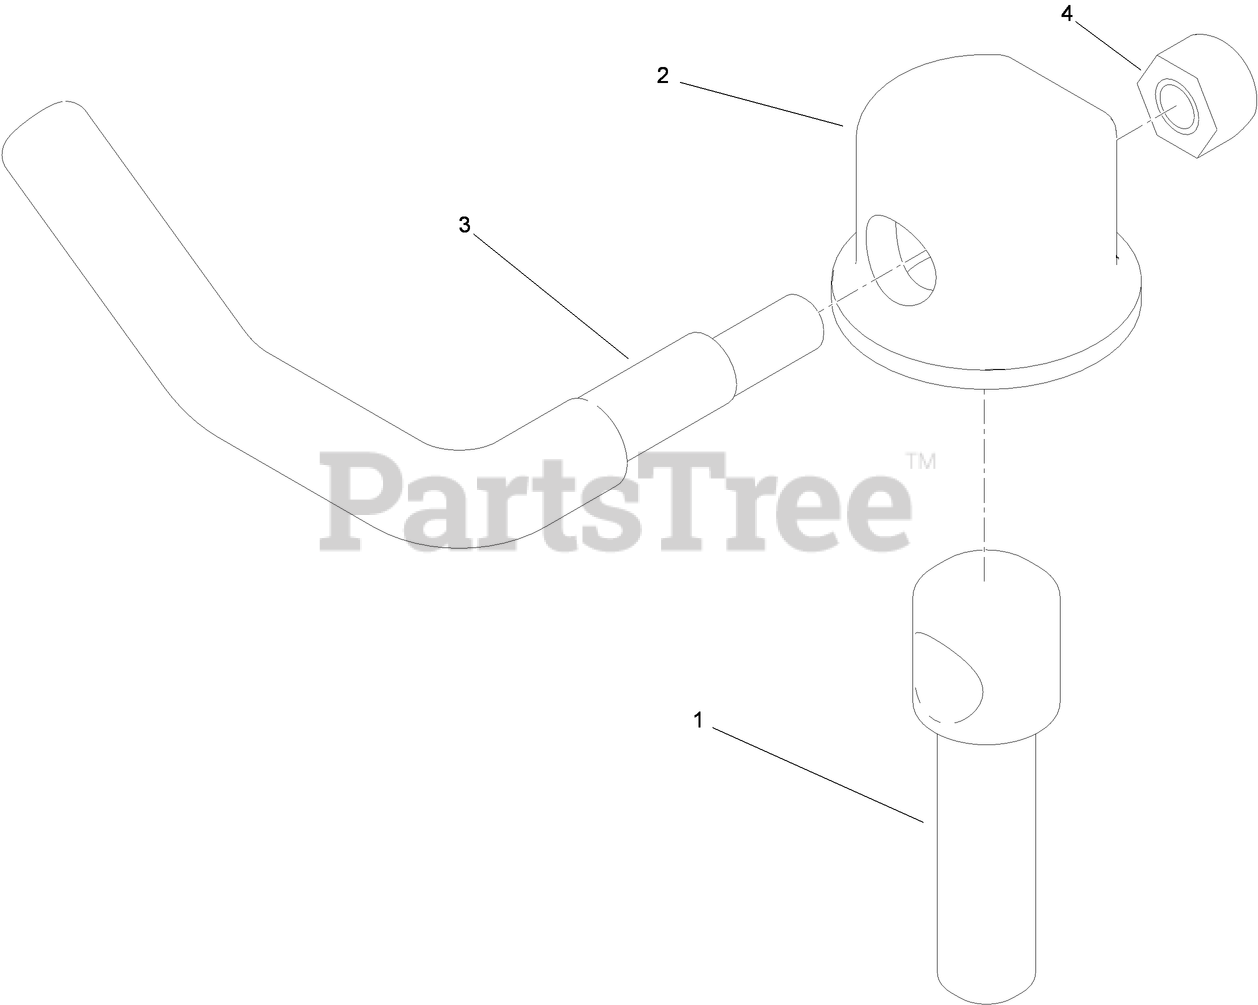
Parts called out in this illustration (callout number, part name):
1	Screw-Lock
2	CAP-LOCK
3	Lever-Lock
4	NUT-LOCK, NI
